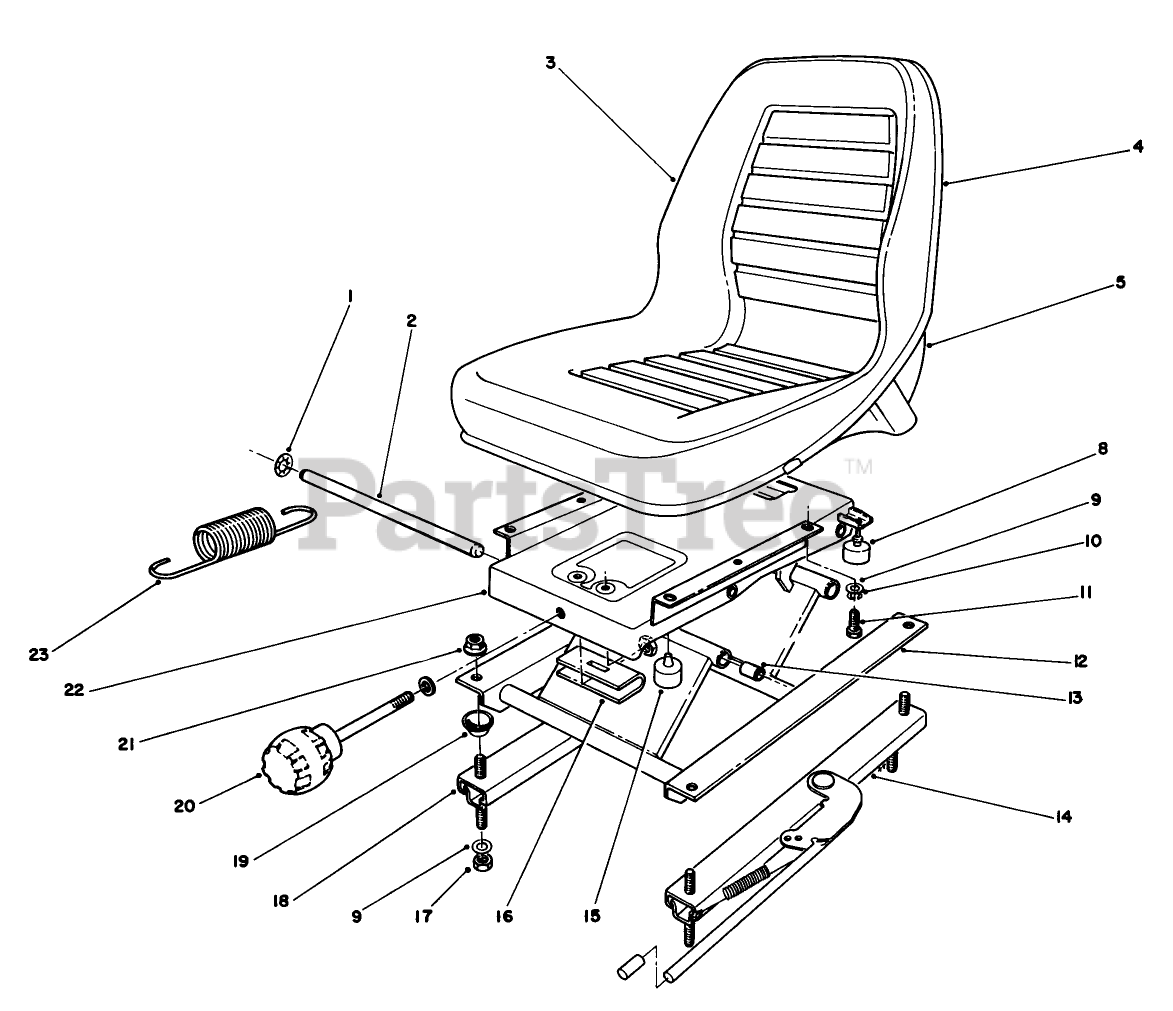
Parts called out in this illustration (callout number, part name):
1	NUT-PUSH
2	SHAFT-PIVOT
3	Cushion-Seat
4	Assembly-Seat (Incl. Ref. #3 & 5)
5	Base
8	BUMPER
9	WASHER-FLAT
10	WASHER-LOCK
11	SCREW-HH
12	FRAME-LOWER
13	SLEEVE-BEARING
14	ADJUSTER W / HANDLE
15	BUMPER-DOWNSTOP
16	SPRING HANGER
17	NUT-LOCK, NI
18	ADJUSTER
19	SPACER-SUSPENSION
20	KNOB-ADJUSTER, TENSION
21	NUT-HF
22	FRAME-UPPER
23	SPRING-EXTENSION
